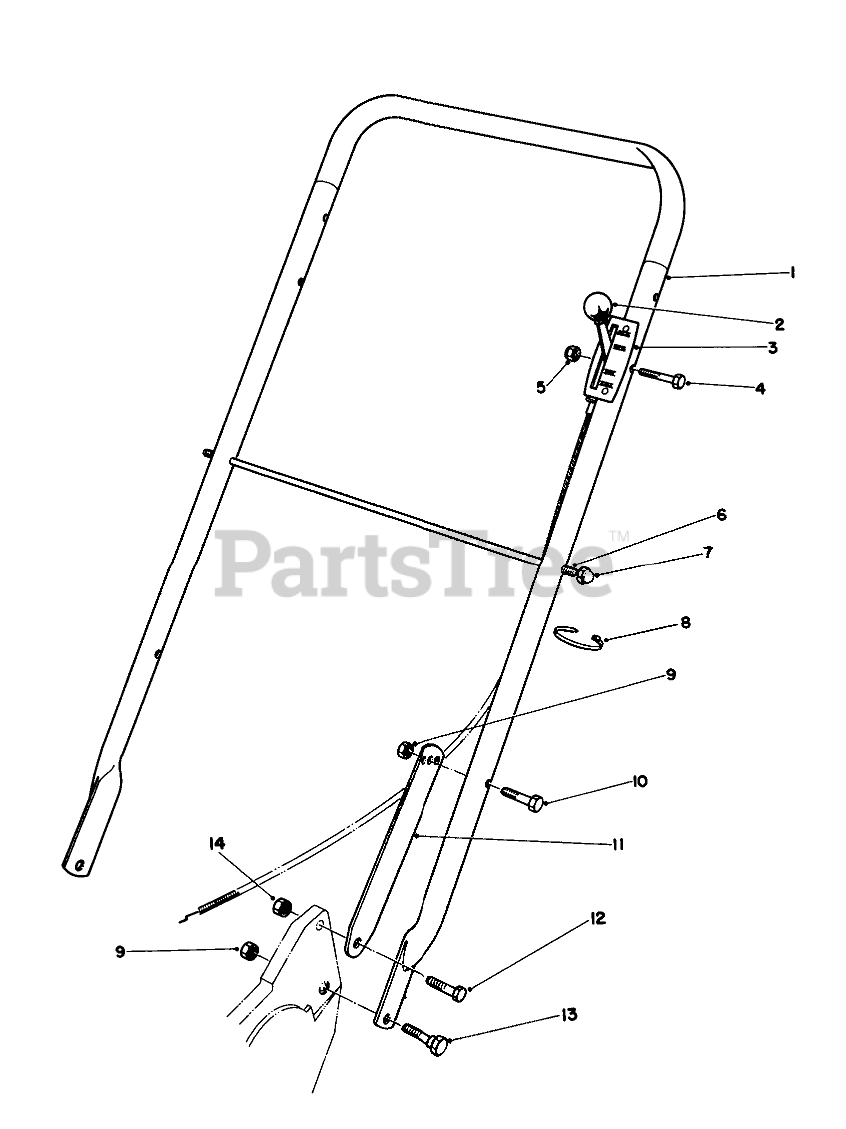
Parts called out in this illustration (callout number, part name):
1	Handle
2	KNOB-CONTROL
3	Control-Throttle (Incl. Ref. #2) Bend Type #1 Sheath Lg.-46.5 Inch Wire Lg.-2.5 Inch
4	SCREW-HH
5	NUT-LOCK, NI
6	ROD-SUPPORT, BAG
7	NUT-CAP
8	TIE-CABLE
9	NUT-LOCK, CONE
10	SCREW-HH
11	Latch-Handle
12	SCREW-HH
13	SCREW-SHOULDER
14	NUT-LOCK, NI
